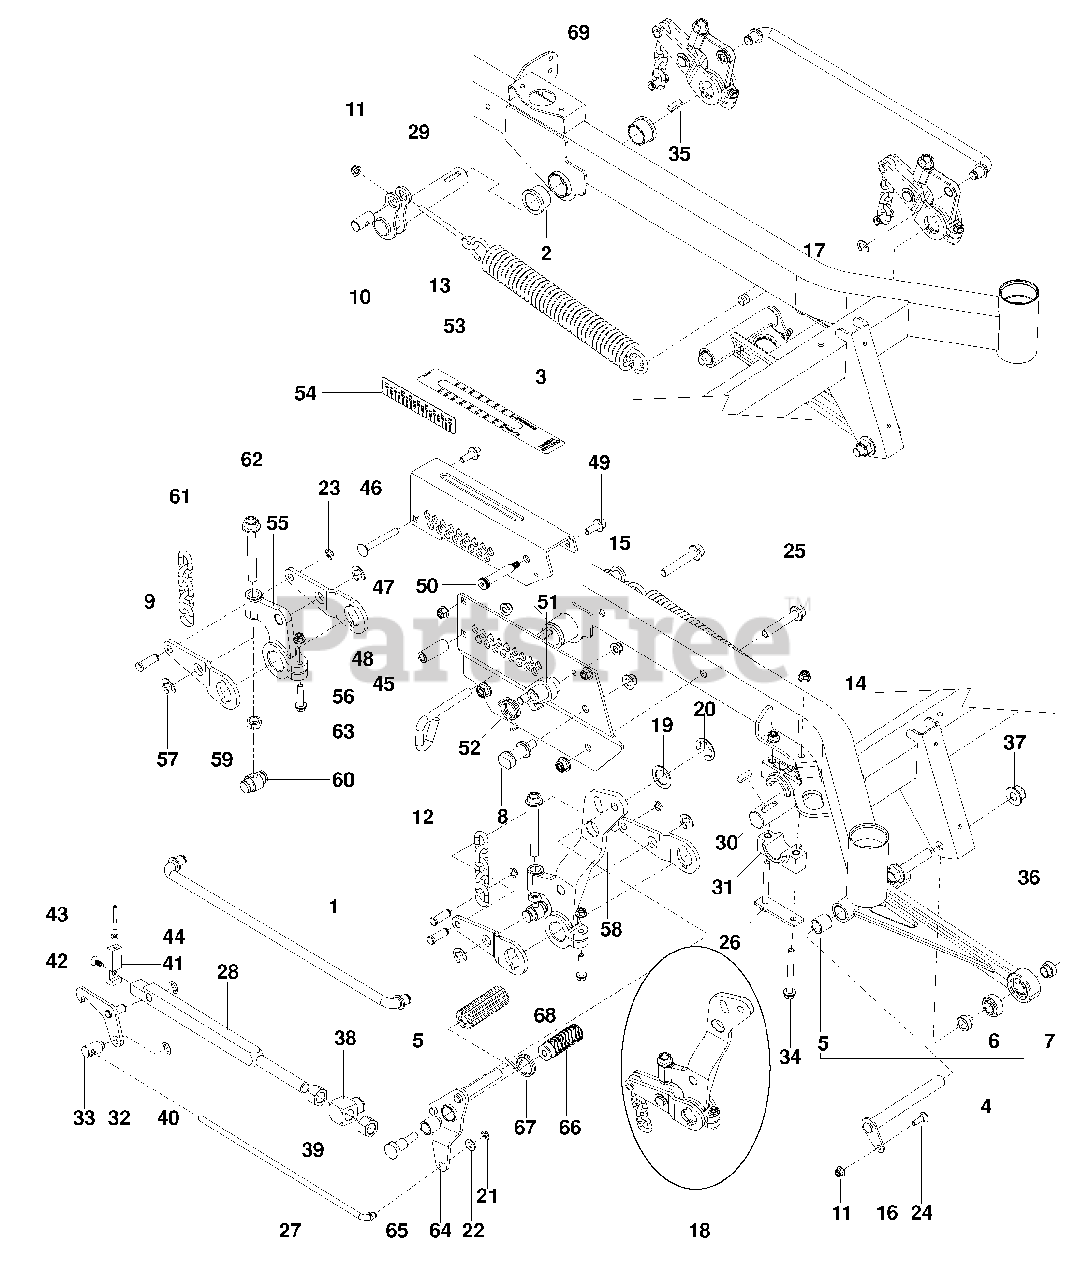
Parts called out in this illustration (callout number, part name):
2	BUSHING, FLANGED 1 1/4 ID
3	SPRING, EXTENSION
4	STRUT ASSY
5	BUSHING 3/4 x 1 SLEEVE
6	BALLJOINT 3/4 SWIVEL
7	SPACER, STRUT
8	GUIDE, HEIGHT BAR
9	PIN 7/16 CLEVIS
10	PIVOT, SPRING
11	NUT 5/16-18 HEX FLANGE NYLOC
12	PIN, HEIGHT
13	EYEBOLT 4 1/2
14	NUT 3/8-16 HEX FLG NYLOC
15	NUT 1/2-13 HEX FLG NYLOC
16	PIN, STRUT
17	E-RING 5/8
18	DECK LIFT LEVER ASSY
19	BUSHING 1" x 14 GA
20	E-RING 1"
21	E- RING 3/8"
22	WASHER, 3/8 SAE FLT
23	E-RING 7/16"
24	BOLT 5/16-18 x 1 RD HD
25	BOLT 1/2-13 x 3 HEX FLG
26	PLATE, PILLOW BLOCK
27	ROD, HEIGHT LATCH
28	BAR, HEIGHT
29	SHAFT, RR LIFT
30	SHAFT, LIFT, FT
31	BLOCK, PILLOW
32	LATCH, HEIGHT
33	SWIVEL, HEIGHT LATCH
34	SCREW 3/8-16 x 3 1/2 HEX FLG
35	KEY 5/16 SQ x 1
36	SCREW 3/8-16 x 1 1/2 HEX HD
37	NUT 5/8-11 FLG NYLOC
38	SWIVEL, HEIGHT BAR
39	NUT 3/4-10 HEX
40	E-RING 1/2"
41	CAP, HEIGHT BAR
42	SCREW 5/16-18 x 3/4 HEX SCKT
43	LINK, INDICATOR
44	NUT 1/4-20 JAM
45	PLATE, INNER HEIGHT
46	PLATE, OUTER HEIGHT
47	BOLT 3/8-16 x 3 RD HD GR2
48	SPACER, HEIGHT PLATE
49	SCREW 3/8-16 x 1 HEX FLG
50	BOLT 1/2 x 2 1/4, 3/8-16 SHLDR
51	LATCH, TRANSPORT
52	SPRING, TORSION
53	DECAL, HEIGHT
54	DECAL, HEIGHT
55	ARM, CAST LIFT
56	SCREW 5/16-18 x 1 1/2 HEX FLG
57	E-RING 3/4"
58	LEVER, DECK LIFT
60	SHAFT, LIFT TRUNION
61	LIFT CHAIN
62	BOLT 1/2-13 x 4 HEX TPBLT
63	NUT 1/2-13 HEX JAM
64	PEDAL, RELEASE
65	BOLT, SHOULDER
66	PAD, FOOT PEDAL
67	SPRING, TORSION
68	PEDAL, DECK HEIGHT
69	DECK LIFT CRANK ASSY
